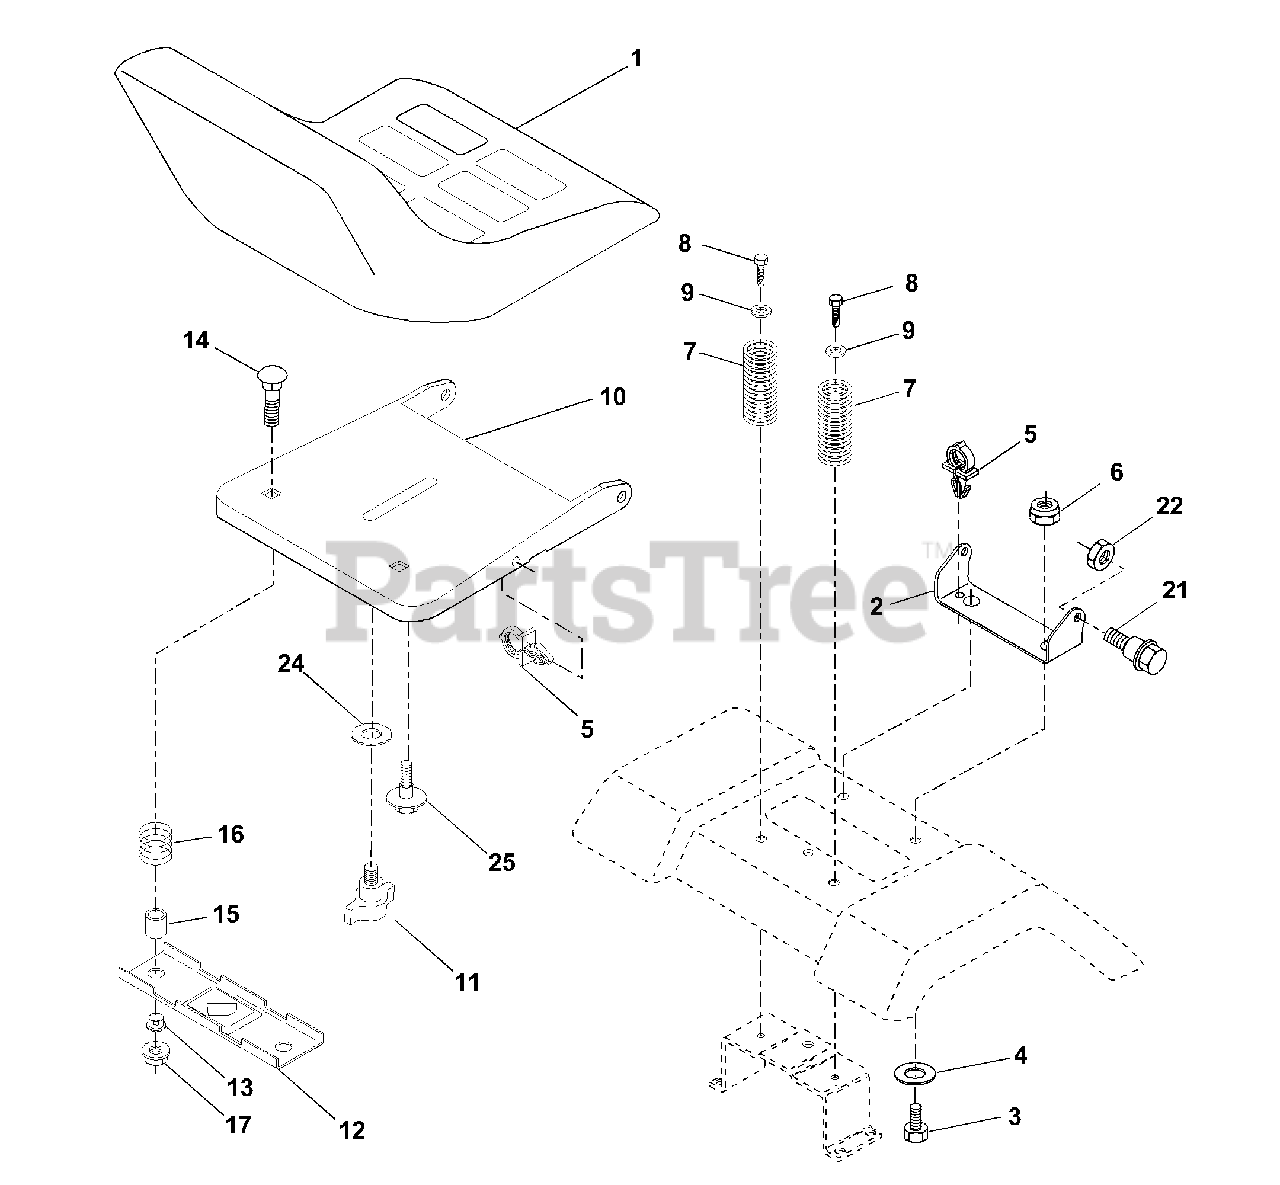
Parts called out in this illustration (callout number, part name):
1	Seat
2	Bracket Pivot Seat 8 720
3	Bolt Fin Hex 3/8-16unc X 1
4	Washer 13/32 X 1 X 10 Ga
5	Clip Push-In
6	Nut Hex w/Ins. 3/8-16 Unc
7	Spring Seat Cprsn 2 250 Blk Zi
8	Screw 3/8-16 X 1
9	Washer 13/32 X 1 X 14 Ga.
10	Pan Seat
11	Knob Seat Adj Wingnut
12	Bracket Mounting Switch
13	Bushing Snap Blk Nyl 50 Id
14	Bolt Rdhd Sqnk 1/4-20x1-1/2
15	Spacer Split 28x 96 Yel Zinc
16	Spring Cprsn 1 27 Blk Pnt
17	Nut Lock 1/4 Lge Flg Gr 5 Zinc
21	Bolt Shoulder 5/16-18 Unc
22	Nut Hex Lock W/Ins 5/16-18
24	Washer 17/32 X 1-3/16 X 12 Ga.
25	Bolt Shoulder 5/16-18 X 62
